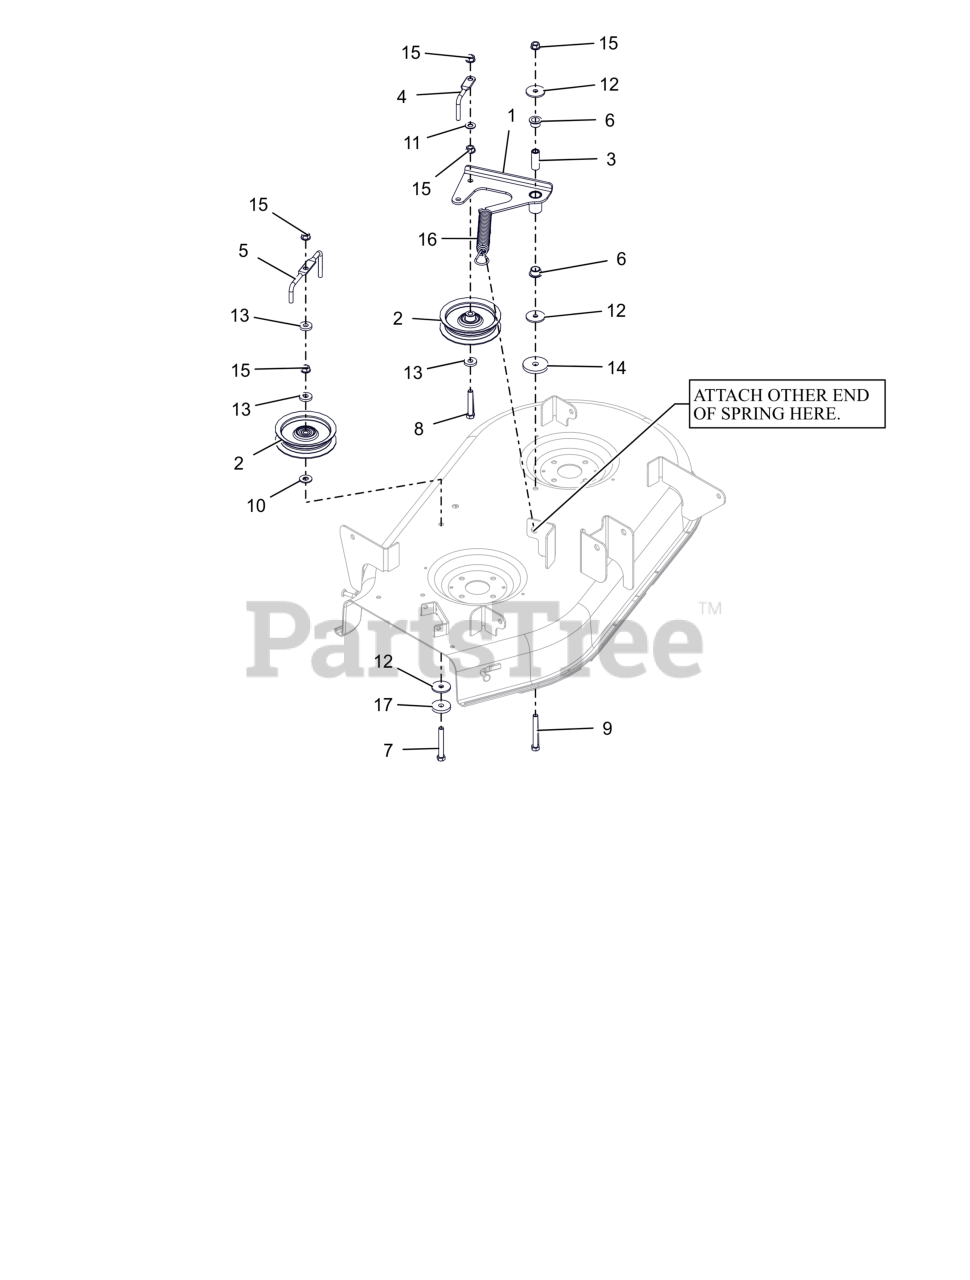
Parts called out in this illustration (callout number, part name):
1	WLDMT, IDLER ARM (ORANGE)
2	IDLER, FLAT - 4.06" X .75"
3	SPACER, .375IDX.625ODX1.66 PM
4	WIREFORM-BELT FINGER
5	BELT FINGER
6	BSHG-FLG, .625X.750X.500X1.00
7	BLT, HEX .38-16X2.75 G5 ZCC
8	BLT,HEX .38-16X2.25 G5 ZCC
9	BLT, HEX .38-16X3.00 G5 ZCC
10	WSHR,FLT .438X1.00X.083 ZCC
11	WSHR,FLT .406X.812X.065 ZCC
12	WSHR, FLT .380X1.50X.125 ZCC
13	WSHR, FLT .406X1.00X.188 ZCC
14	WSHR, FLT .469X2.00X.250 ZCC
15	NUT-LK-CTR-FLG .375-16 GF ZCC
16	SG-TENS .135X.98X6.0 WLD 62
17	WSHR, FLT .406X1.50X.245 ZCC
